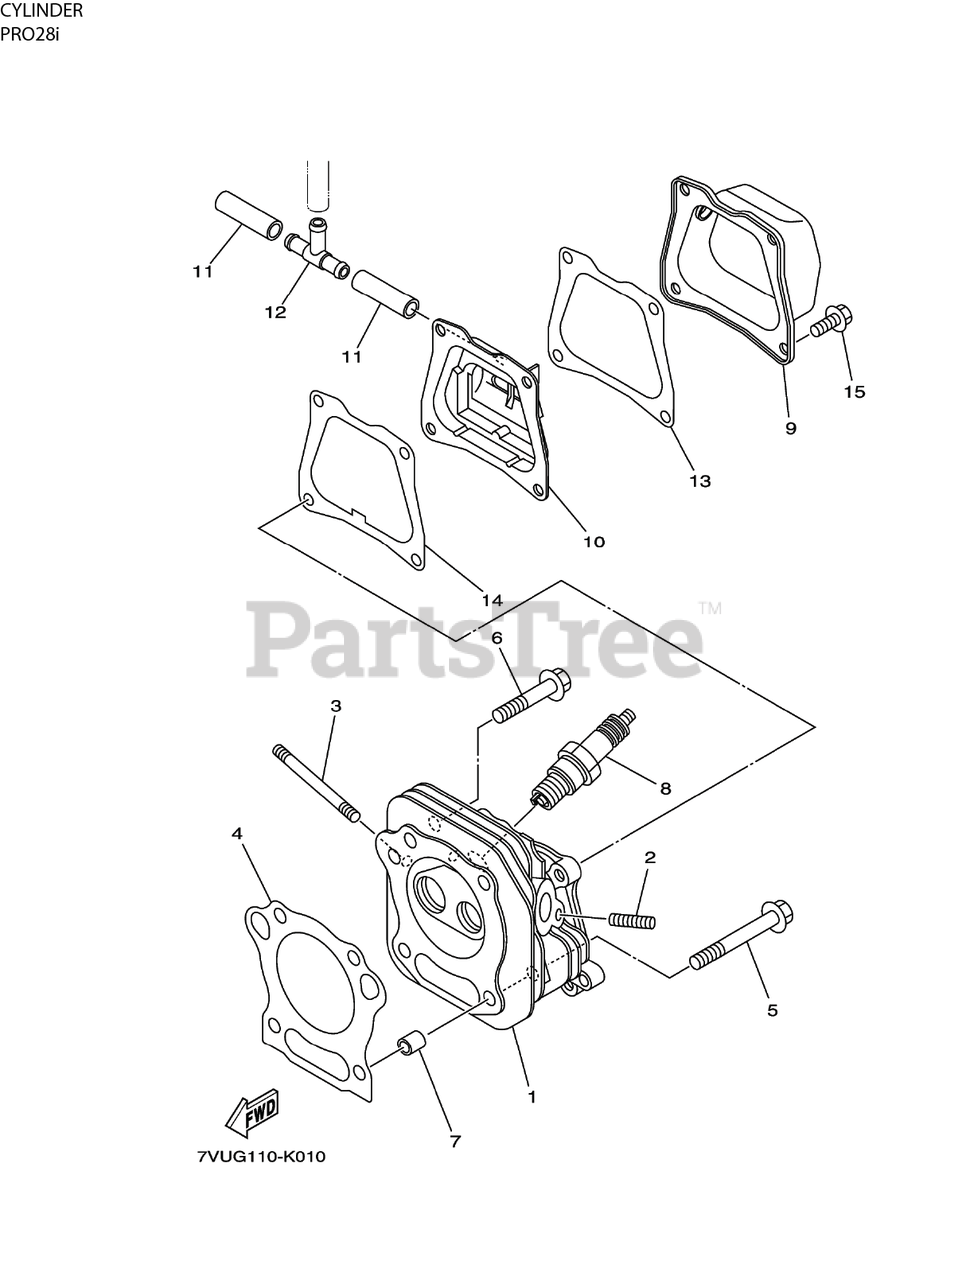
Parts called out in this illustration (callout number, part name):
1	HEAD, CYLINDER
2	STUD BOLDT
3	STUD, BOLDT
4	GASKET, CYLINDER HEAD
5	SCREW - BOLT FLANGE
6	SCREW - PAN HEAD
7	PIN, DOWEL
8	SPARK PLUG
9	COVER, AIR CLEANER - CYLINDER HEAD
10	BREATHER ASSEMBLY
11	HOSE - PIPE, BREATHER
13	GASKET, BREATHER COVER
14	GASKET, HEAD COVER
15	SCREW - BOLT FLANGE
